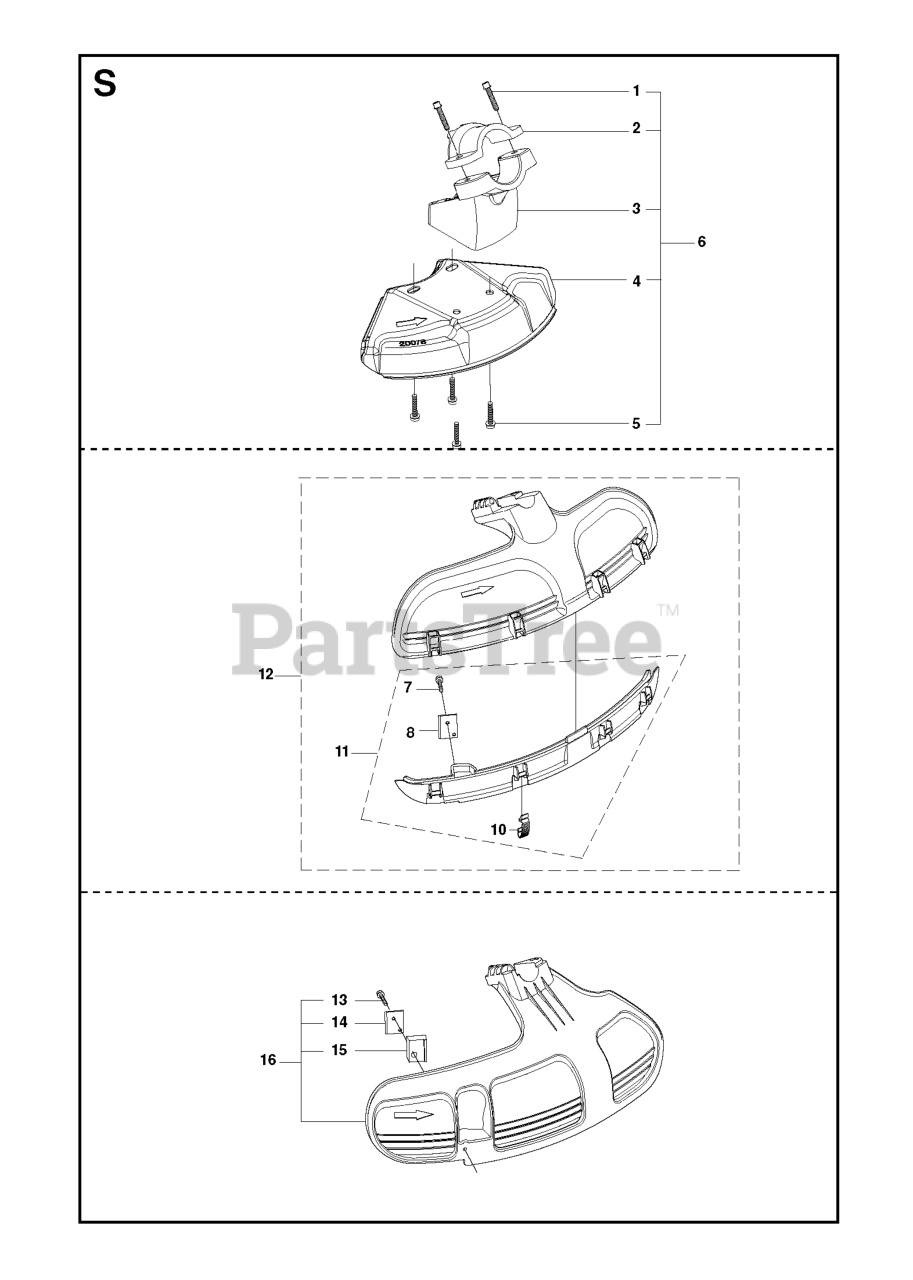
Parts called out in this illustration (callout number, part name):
3	ADAPTER
4	RP BLADE GUARD
6	PROTECTOR
8	LINE CUTTER
11	SPLASH GUARD
12	COMBI PROTECTOR
14	LINE CUTTER
15	DISTANSBLOCK
